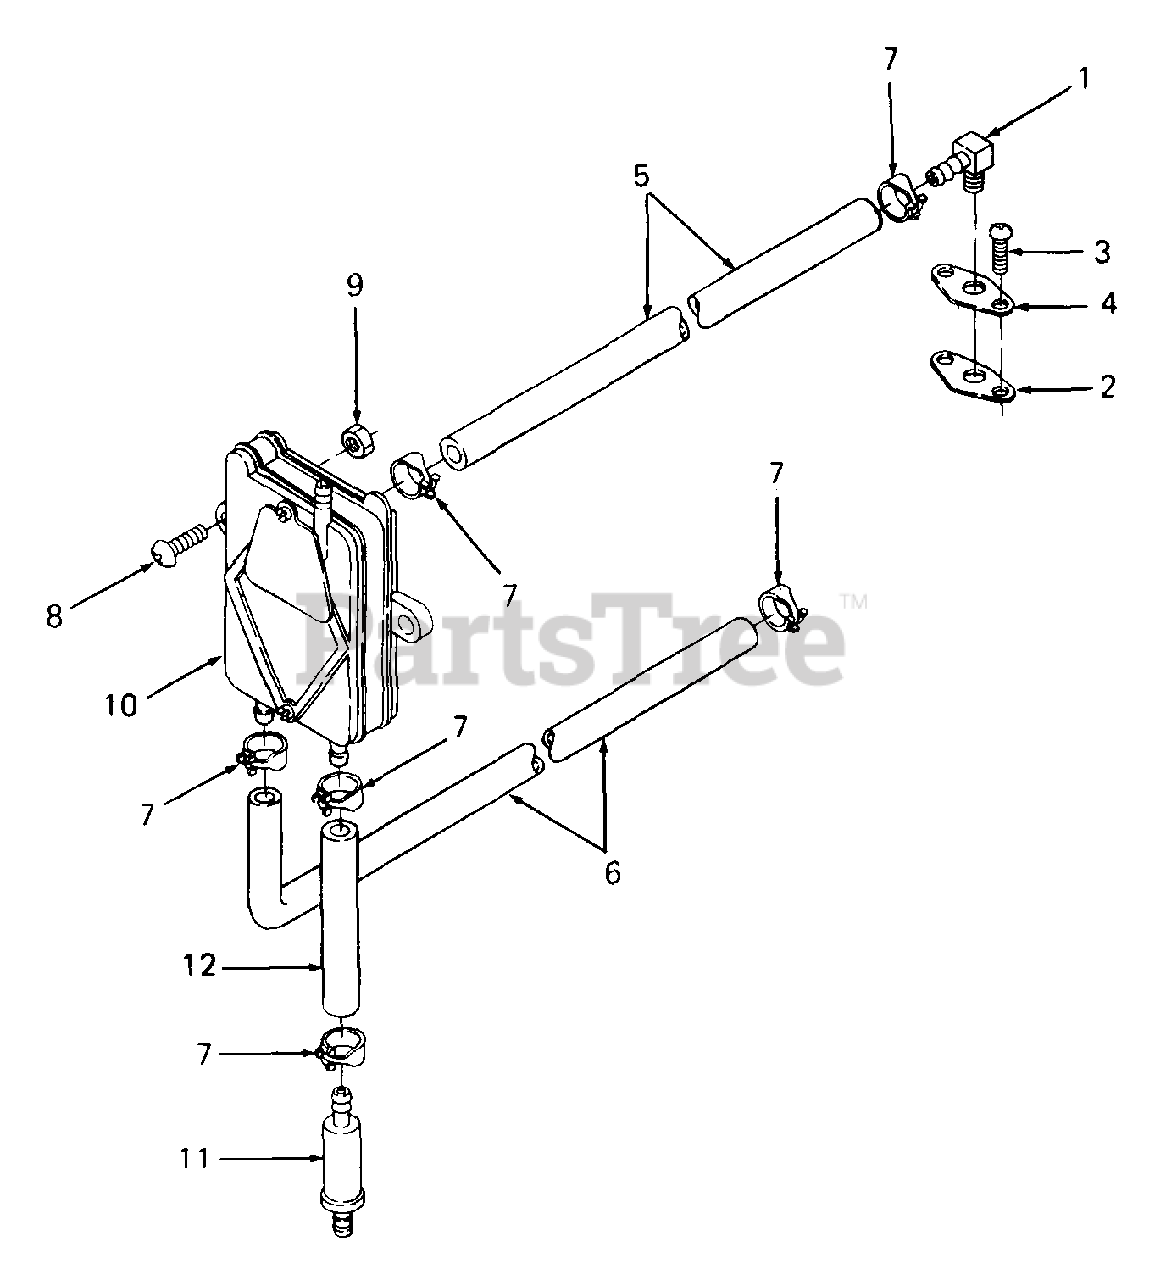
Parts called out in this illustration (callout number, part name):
1	Connector, Hose
2	Gasket, Fuel Pump
3	Screw, Pozidriv Th, 1/4-20 x .62 Lg
5	Line, Fuel
6	Line, Fuel
7	Clamp, Hose
8	Screw, Truss Mach, 10-24 x .62
9	Nut, Hex Center Lock, 10-24
10	Pump, Fuel
11	Filter, Fuel
12	Line, Fuel, 5" Lg
